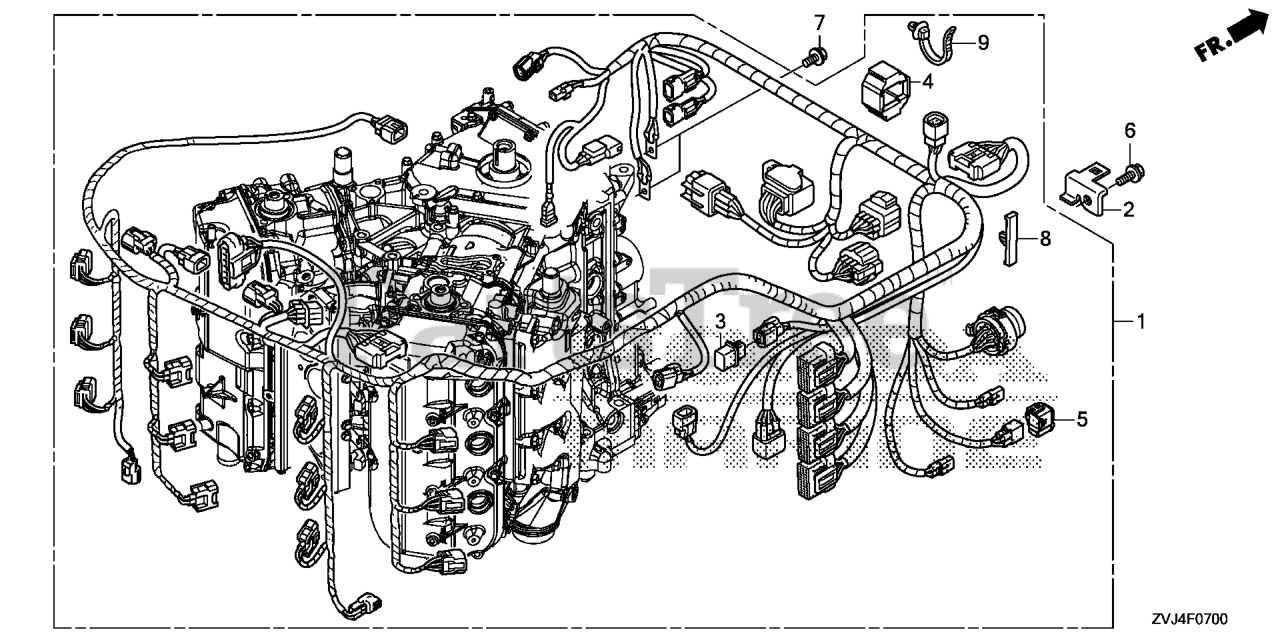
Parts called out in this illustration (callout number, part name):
1	WIRE HARNESS ASSY., MAIN
1	HARN, MAIN WIRE
2	BRACKET, JUNCTION CONNECTOR
3	TERMINATOR ASSY.
4	SUSPENSION, CONNECTOR
5	CAP, DUMMY (WPC 4P 090 M) (RED)
6	BOLT, FLANGE (6X14)
7	BOLT, FLANGE (6X12)
8	CLIP, WIRE HARNESS
9	CLIP, HARNESS BAND (145MM) (BLACK)
